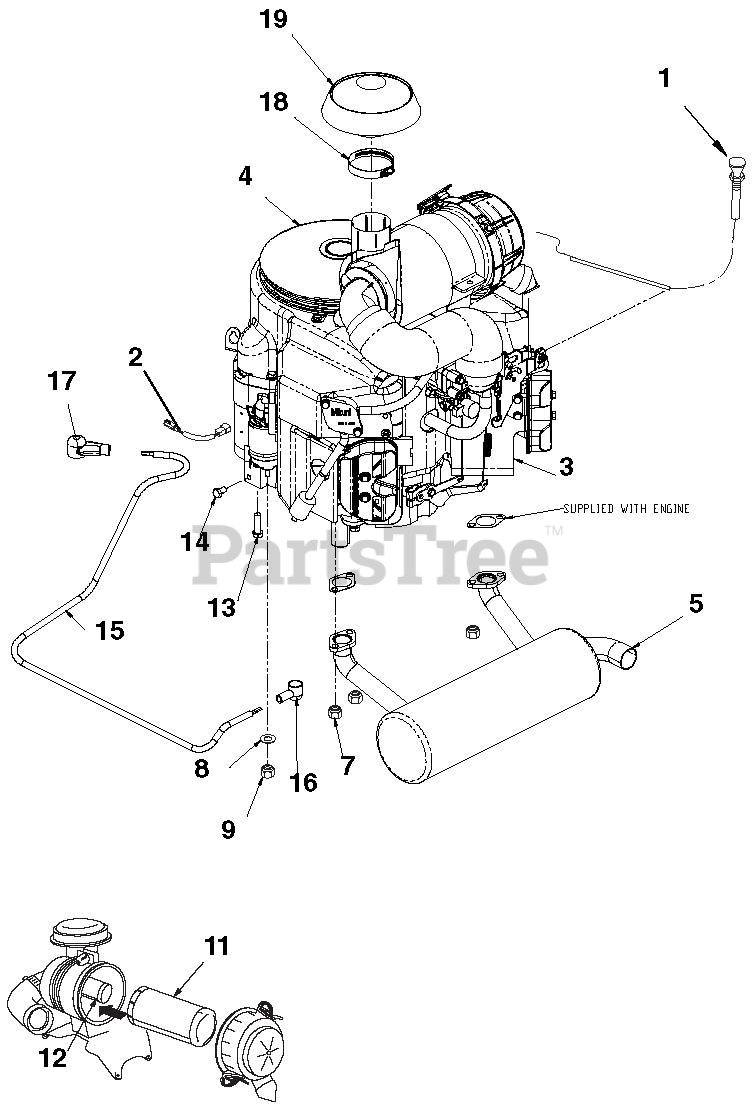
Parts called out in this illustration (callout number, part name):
1	CABLE, CHOKE 48.0"
2	LEAD - STARTER SOLENOID
3	FILTER,OIL - KAW
4	ENGINE, KAWASAKI FX751 (27HP)
4	ENGINE, KAWASAKI FX850 (31HP)
5	MUFFLER - 31HP KAWASAKI VERT.
6	WIRE HARNESS
7	LOCKNUT, 5/16-18 CROWN Y
8	WASHER, M8 SPRG LOCK Y
9	NUT, M8X1.25 HEX GR8.8 Y
11	ELEMENT-OUTER - KAWASAKI
12	ELEMENT-INNER - KAWASAKI
13	BLT-HEX.38-16X1.25FTHG5 EP30YZ
14	BOLT, M8X1.25X14 HEX 8.8 Y
15	CABLE, BATTERY - 42" POSITIVE
16	BOOT, EYELET TERMINAL
17	BOOT, BATTERY TERMINAL-RED
18	CLAMP, HOSE 2.75 DIA WORM
19	RAIN CAP, AIR CLEANER (2.5")
